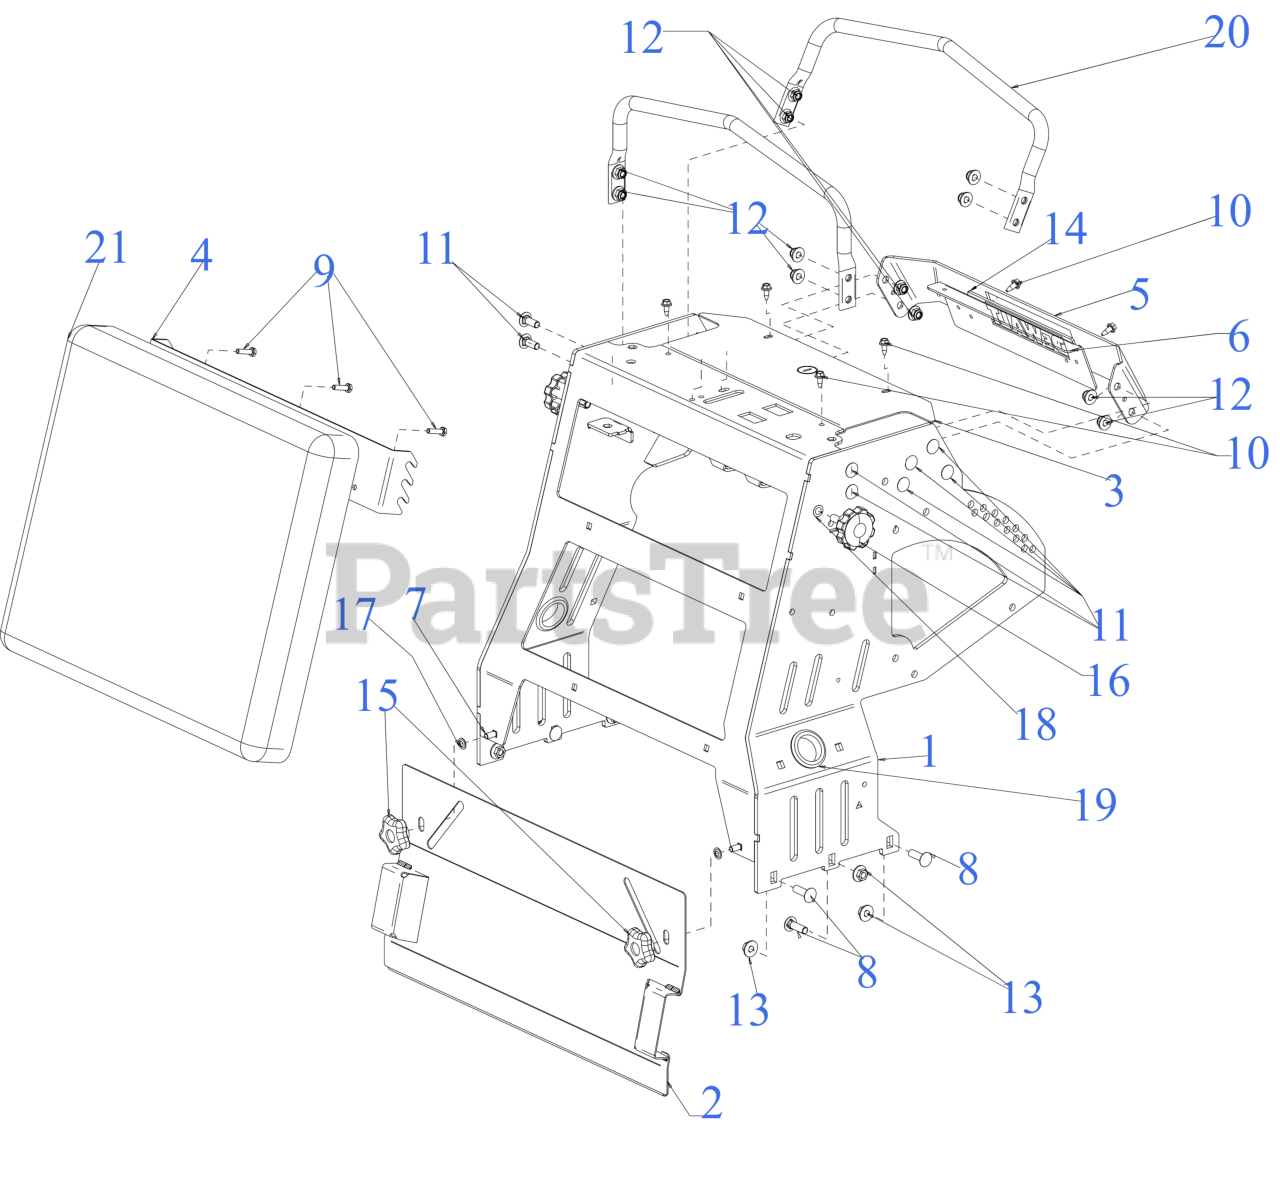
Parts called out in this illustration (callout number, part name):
1	CONTROL BASE
2	PANEL COVER
3	DASH PANEL
4	PAD MOUNT
5	CONTROL BASE (FRONT)
6	DASH SUPPORT
7	CARRIAGE BOLT 5/16-18 x .75
8	CARRIAGE BOLT 3/8-16 X1.25 GR5
9	SCREW 1/4-20 X1.00 GR5
10	SCREW 1/4-20X.625
11	CARRIAGE BOLT 3/8-16 x 1.00 GR5
13	FLANGE LOCK NUT
14	DEWALT LOGO (DIE CAST)
15	STAR KNOB 5/16-18
16	STAR KNOB 3/8-16
17	PUSH NUT
18	RIV NUT 3/8-16
19	RUBBER GROMMET (1.50X2.13X.563)
20	TUBE
21	LEG PAD
